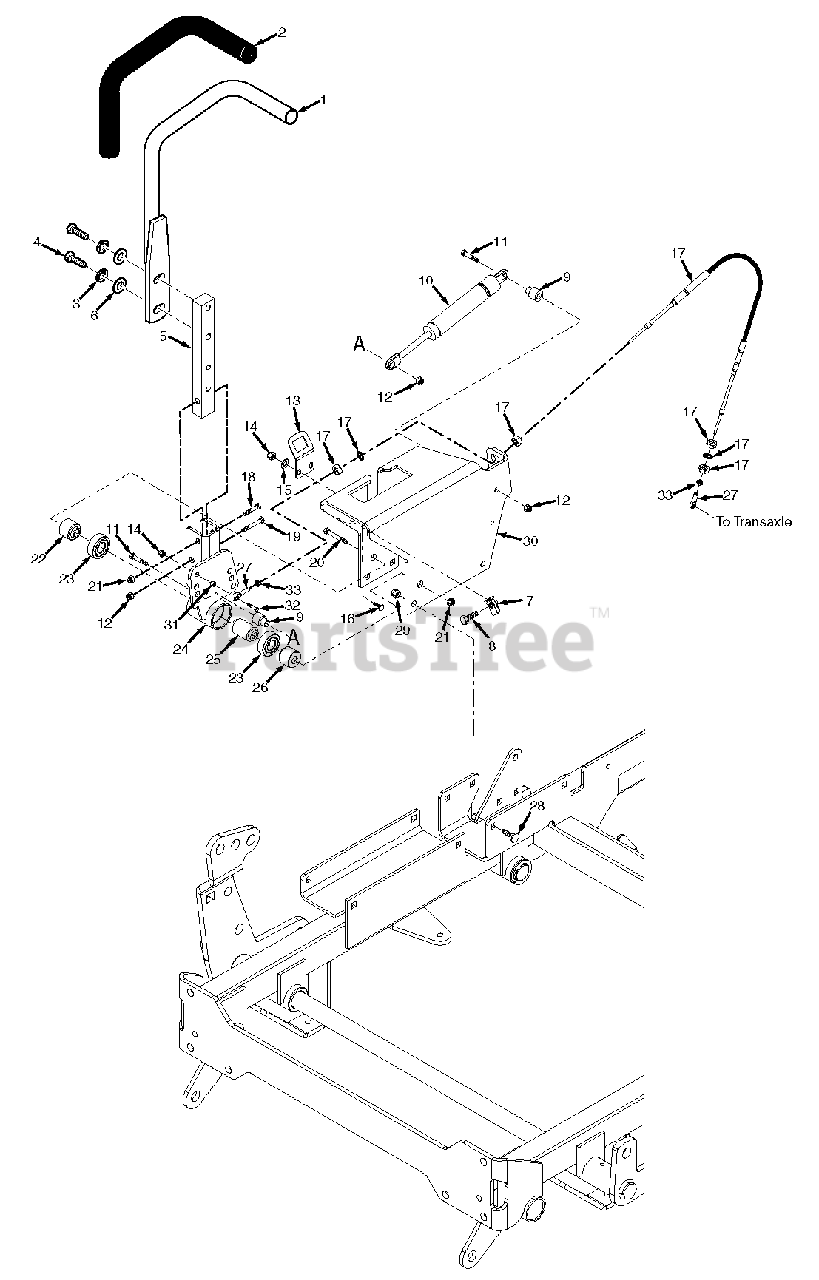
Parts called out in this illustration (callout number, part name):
1	Handle Bar w/Grip
2	Grip, Control Handle
3	Lockwasher, 3/8" Spring
4	Bolt, Hex Head 3/8-16 x 1-1/4'
5	Bar, Control Lever
6	Flatwasher, 3/8-.391 x .938 x .105
7	U-Nut, 3/8-16
8	Bolt, Hex Head 3/8-16 x 2" Special
9	Spacer
10	Damper
11	Bolt, Hex Head 5/16-18 x 1-1/2"
12	Nut, Elastic Stop 5/16-18
13	Bracket, Operator Presence Switch
14	Nut, Elastic Stop 1/4-20
15	Flatwasher, 1/4-.312 x .750 x .065
16	Bolt, Carriage 1/4-20 x 3/4"
17	Control Cable, Hydro
18	Bolt, Hex Head 3/8-16 x 2"
19	Bolt, Hex Head 5/16-18 x 2"
20	Bolt, Hex Head 3/8-16 x 4-1/2"
21	Nut, Elastic Stop 3/8-16
22	Spacer, Controls
23	Bearing
24	Pivot Weldment, Control Arm LH
24	Pivot Weldment, Control Arm RH
25	Spacer, Bearing
26	Spacer, Controls
27	Rod End, 1/4-28 RH Thread
28	Bolt,Carriage 5/16-18 x 1"
29	Nut, Serrated Flange 5/16-18
30	Bracket Weldment, Control Lever RH w/Decal
30	Bracket Weldment, Control Lever LH w/Decal
31	Spacer
32	Bolt, Hex Head 1/4-20 x 1-1/4"
33	Nut, Jam 1/4-28 UNF
